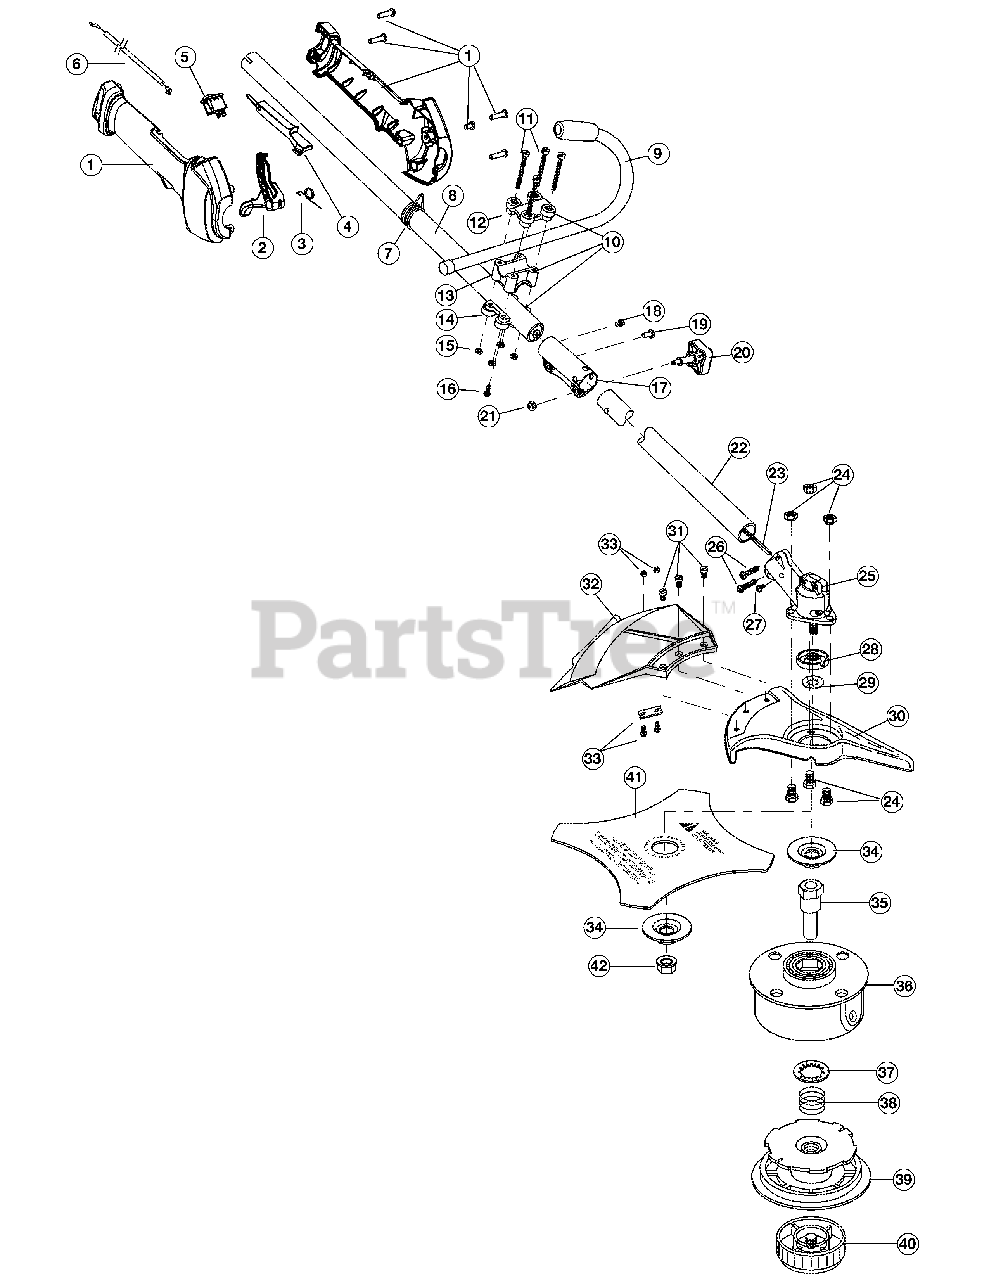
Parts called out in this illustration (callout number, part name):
1	Throttle Housing Assembly (includes 2-5)
2	Throttle Trigger
3	Throttle Trigger Spring
4	Throttle Trigger Lock-Out
5	Switch Assembly
6	Throttle Cable Assembly
7	Harness Clip
8	Upper Drive Shaft Housing Assembly
9	J-Handle Assembly
10	Handle Bracket Assembly (includes 11-16)
12	Upper Handle Clamp
13	Middle Handle Clamp
14	Lower Handle Clamp
16	Anti-Rotation Screw
17	Split Boom Coupler (includes 18-21)
20	Adjustment Knob (includes 21)
21	Knob Retaining Nut
22	Lower Drive Shaft Housing Assembly
23	Lower Flexible Drive Shaft
24	Shield Mount Screw Assembly
25	2 piece Gearbox Assembly (includes 26-29)
26	Gearbox Mounting Hardware
27	Anti-Rotation Screw
28	Blade Driver
29	Palnut
30	Blade Shield/Shield Mount
31	Shield Mounting Screw
32	Shield Assembly (includes 33)
33	Blade Assembly
34	Retaining Washer
35	Spool Shaft
36	Outer Spool Assembly (includes 37)
37	Retainer
39	Inner Reel
40	Bump Head Knob Assembly
41	4-Tooth Blade
42	Nut
